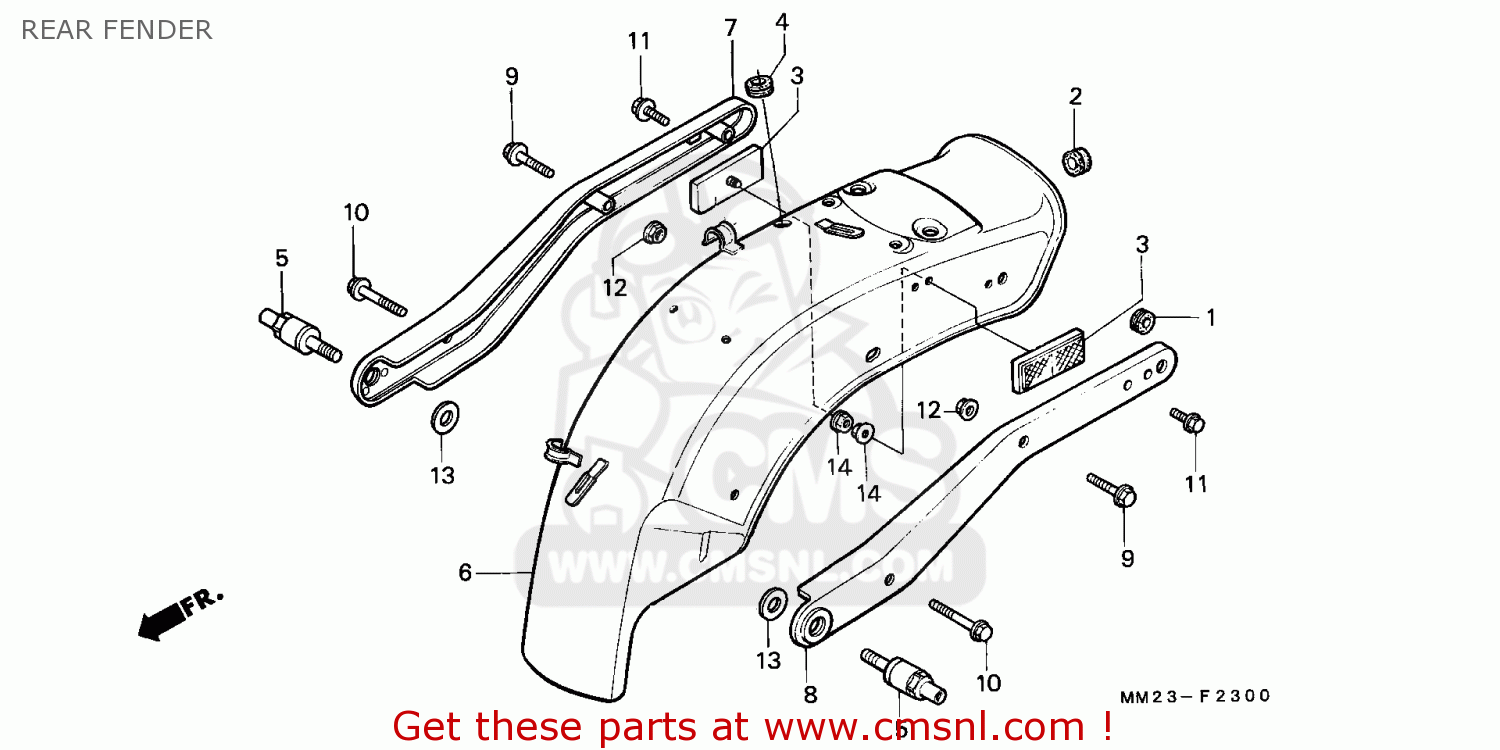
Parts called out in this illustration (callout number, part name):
1	RUBBER,CUSHION
2	GROMMET,AC WIRE
4	GROMMET B,TUBE
5	BOLT,L RR CUSHION
6	FENDER COMP*NH-1*
7	PLATE, R. TAIL
8	PLATE, L. TAIL
9	BOLT,SPECIAL FLAN
10	BOLT,SPECIAL FLAN
11	BOLT,SPECIAL FLAN
12	NUT,SPECIAL,8MM
13	WASHER,34X15.5MM
